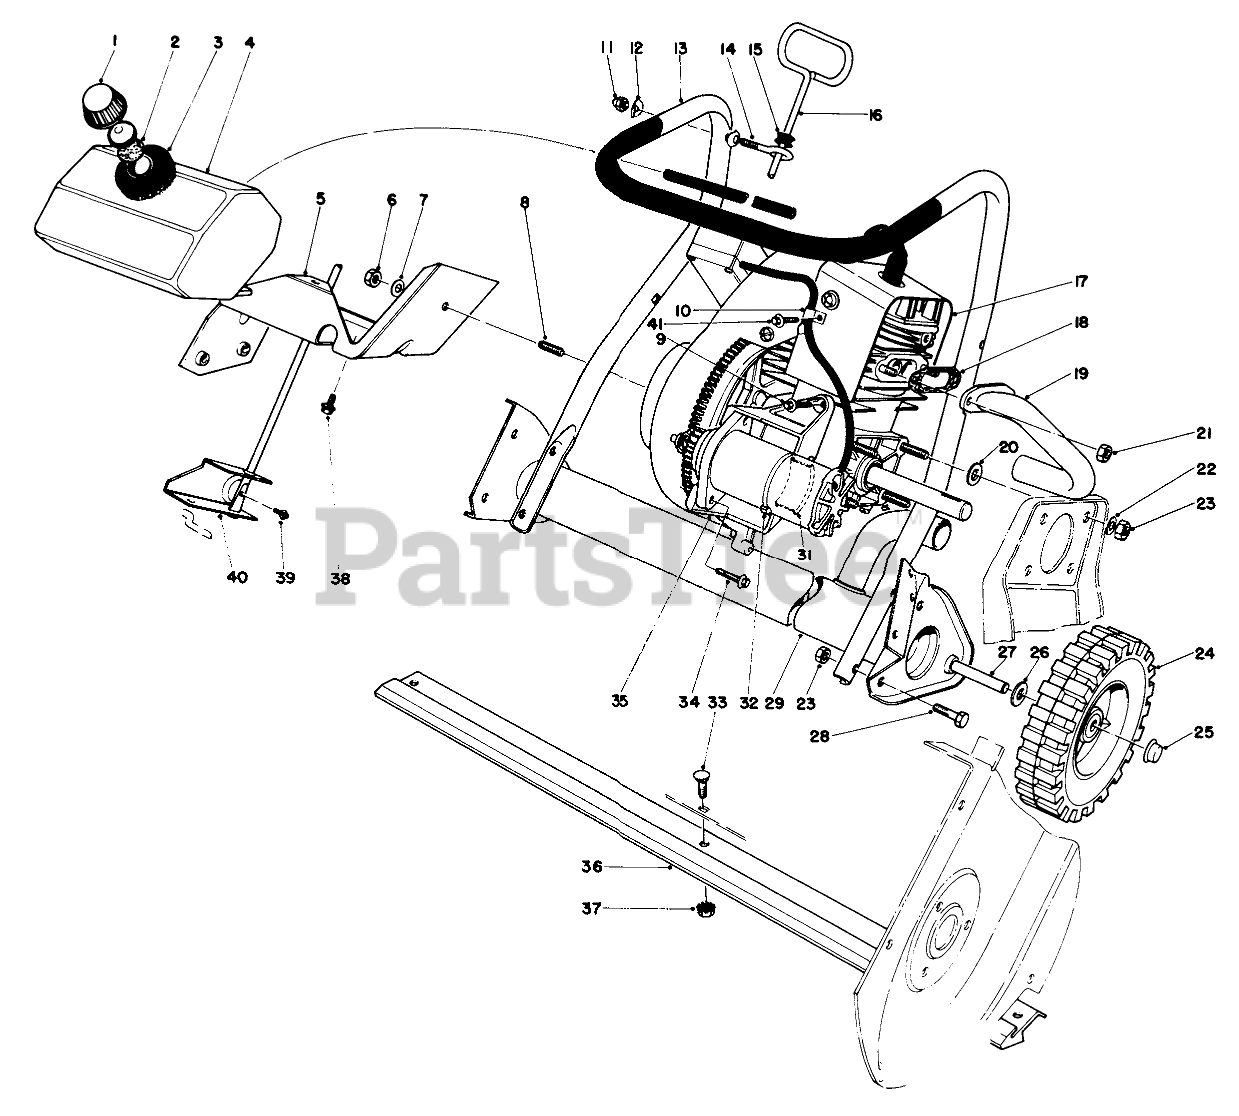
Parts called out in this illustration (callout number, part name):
1	Gas Cap (Incl. Ref. #2)
2	GAS CAP GASKET
3	FOAM PAD
4	Gas Tank
5	Rear Support Engine
6	NUT-LOCK, CONE
7	WASHER
9	Screw
10	CABLE CLAMP
11	NUT-CAP
12	WASHER
13	Lower Handle
14	Bolt-Eye
15	GROMMET
16	Rod Vane Adjustment
17	Engine
18	EXHAUST GASKET
19	Exhaust Pipe
20	WASHER-FLAT
21	NUT-LOCK, CONE
22	WASHER-PLAIN
23	NUT-LOCK, NI
24	WHEEL
25	RETAINER-PUSH ON
26	WASHER-FLAT
28	SCREW-HH
29	EXHAUST MUFFLER ASM
31	RR MOTOR SUPPORT
32	TIE-CABLE
33	BOLT-CARR
34	SCREW-FLOW, TAPTITE
35	Bracket-Motor Mount
36	SCRAPER
37	NUT-KEPS
38	SCREW
39	SCREW
40	Bracket-Vane Adjustment
41	NUT-KEPS
